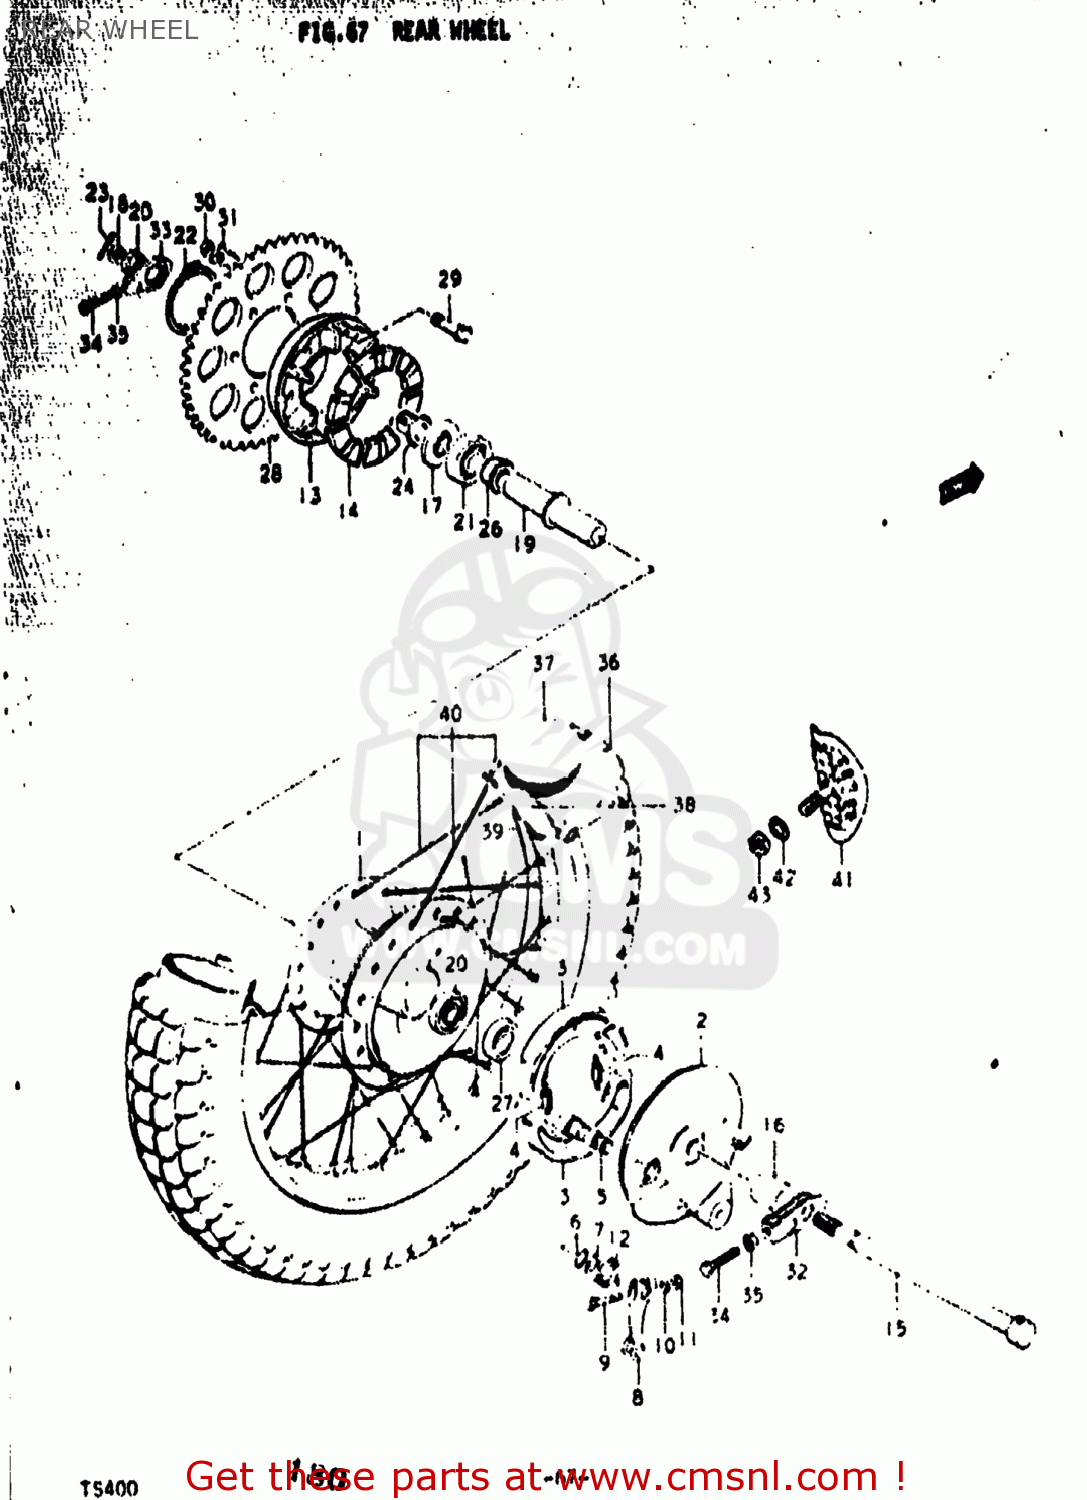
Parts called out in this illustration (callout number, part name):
1	HUB,REAR
2	PANEL,REAR HUB
3	SHOE,BRAKE
4	SPRING
5	CAM,FRONT BRAKE
6	O-RING,BOSS
7	WASHER (15X24X1.6)
8	LEVER,REAR BRAKE CAM
9	BOLT
10	WASHER
11	NUT
12	SPRING
13	DRUM,REAR SPROCKET MOUNT
14	ABSORBER,RR WHEEL HUB SHOCK
15	AXLE,REAR
16	SPACER (15.2X26X20)
17	SPACER,REAR AXLE,RIGHT
18	NUT
19	SPACER,REAR HUB BEARING
20	BEARING, RH
21	BEARING
22	CIRCLIP
23	PIN 30X40
24	SPACER,REAR AXLE,LEFT
25	NUT
26	SPACER,REAR HUB BEARING
27	OIL SEAL
28	SPROCKET,RR
29	BOLT(8X33.5)
30	NUT
31	WASHER
32	ADJUSTER,CHAIN
33	ADJUSTER,CHAIN
34	BOLT
35	NUT
36	TIRE
37	TUBE ASSEMBLY,WHEEL,INNER
38	PROTECTOR,WHEEL,INNER
39	RIM,WHEEL
40	SPOKE SET,REAR
41	STOPPER,BEAD
42	WASHER
43	NUT
